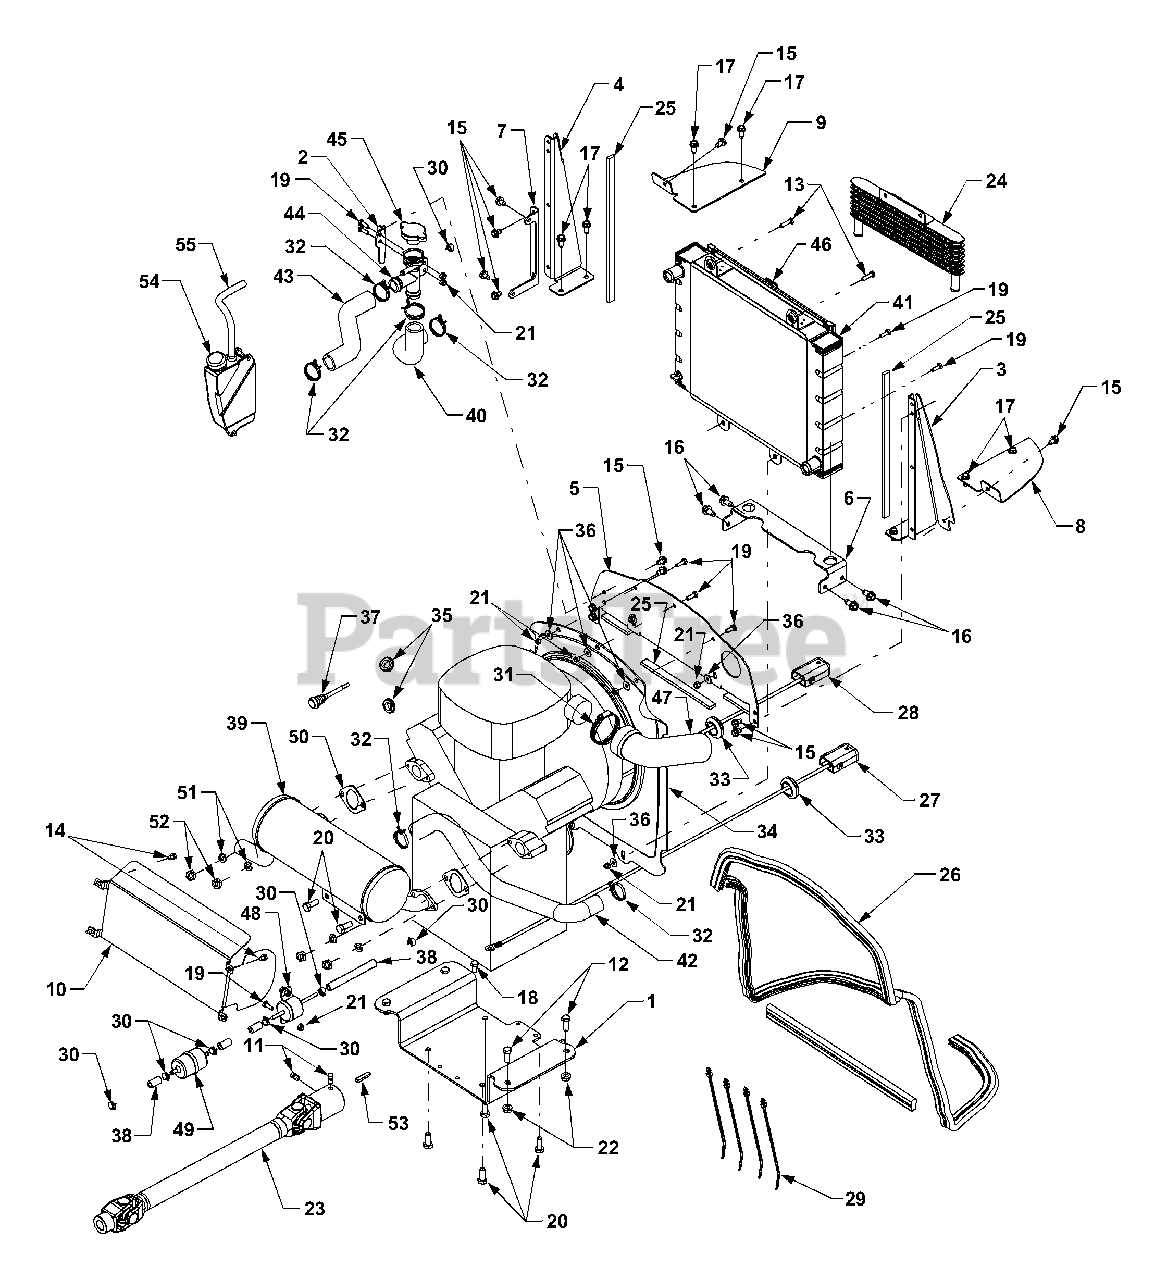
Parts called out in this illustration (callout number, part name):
1	Plate, Engine Mtg.
2	Bracket, Filler Neck
3	Bracket, Radiator Mtg. RH
4	Bracket, Radiator Mtg. LH
5	Plate, Radiator Baffle
6	Bracket, Radiator Mtg.
7	Bracket, Ovrflw Bottle Mtg.
8	Plate, Baffle RH
9	Plate, Baffle LH
10	Shield, Heat
11	Screw, Square Hd. Set, 3/8-16
12	Screw, Hex Cap, 3/8-16 x 1.0 GR5
13	Screw, Hex Cap, 1/4-20 x 1.0 GR5
14	Screw, Hex Wash Hd Tapp 1/4-20 x .5
15	Screw, Hex Wash Hd Tapp 5/16-18 x .5
16	Screw, Hex Wash Hd Tapp 3/8-16 x .75
17	Screw, Hex Wash Hd Tapp 5/16-18 x .75
18	Screw, Hex Cap, M8-20 x 16
19	Screw, Hex Cap, 1/4-20 x .75 GR5
20	Screw, Hex Cap, M10 x 1.5 x 25
21	Nut, Hex Nylon Insert Lock 1/4-20 GR8
22	Nut, Hx Flnge Lock, 3/8-16
23	Shaft, Drive
24	Cooler, Oil
25	Tape, Foam, .625 wide 42in.
26	Seal, Heat Baffle 96in.
27	Wire, Battery Neg.
28	Wire, Battery Pos.
29	Tie, Cable - Push Mount
30	Clamp, Hose
31	Clamp, Hose - Adjustable
32	Clamp, Hose
34	Shroud, Fan
36	Washer, Flat, .28 x .74 x .063
37	Cable, Choke Control
38	Fuel Line 5/16 ID 94in.
40	Hose, Filler to Radiator
42	Hose, Lower Radiator
43	Hose, Engine to Filler Neck
44	Filler Neck, Remote Radiator
45	Cap, Remote Filler
46	Screen, Radiator
47	Hose, Intake Air
49	Filter, Fuel
50	Gasket, Exhaust
51	Washer, Spring
53	Key, Crankshaft
54	Bottle, Over Flow
